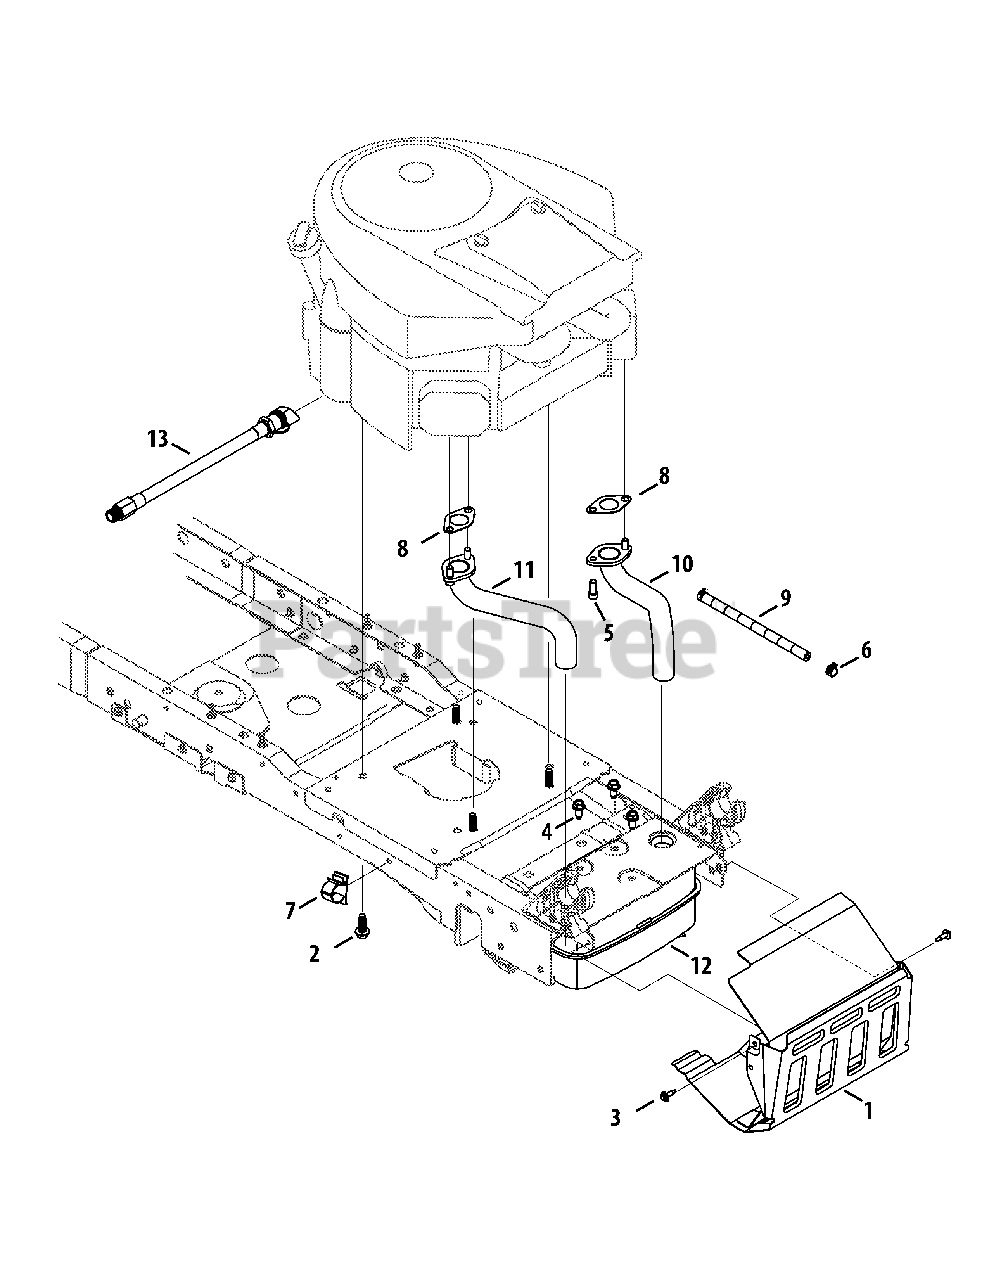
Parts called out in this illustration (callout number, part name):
1	Shield Ass’y, Muffler
2	Screw, Self-tapping, 3/8-16, 1.0
3	Screw, M6-1 x .625
4	Screw, Self-tapping, M8-1.25, .750
5	Screw, Sokt Head, 5/16-18, .750
6	Clamp, Hose, .490 Dia.
7	Push Mount Wire Clip, .750
8	Exhaust Gasket
9	Hose, Fuel, Low Permeation, 1/4
10	Exhaust Pipe, LH
11	Exhaust Pipe, RH
12	Muffler
13	Drain, Oil
